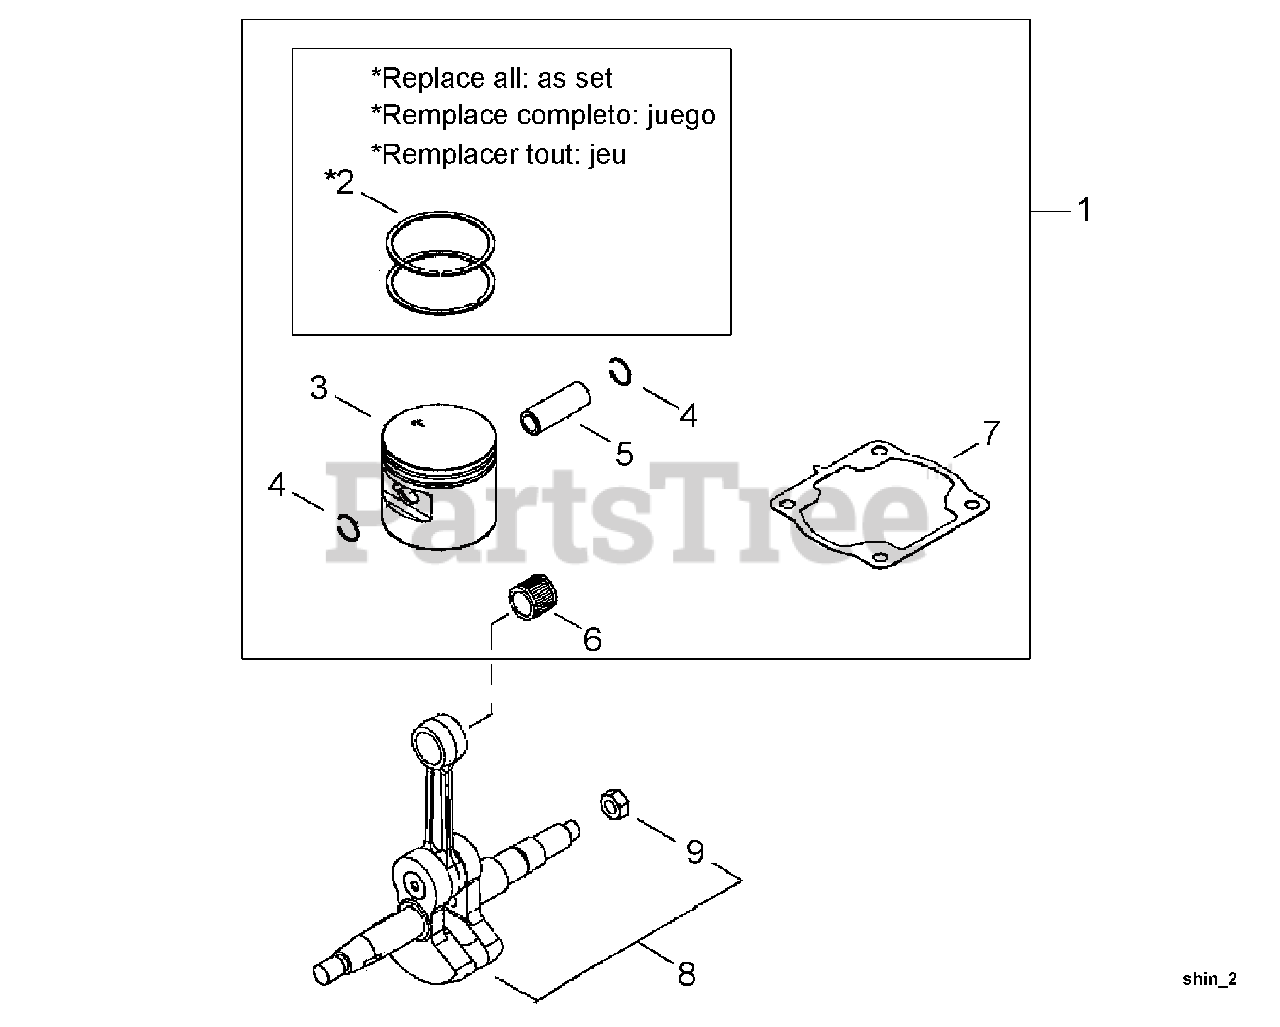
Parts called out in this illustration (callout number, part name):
1	PISTON KIT
2	RING, PISTON
4	RING, SNAP
5	PIN, PISTON 10
6	BEARING, NEEDLE
7	GASKET, CYLINDER
8	CRANKSHAFT ASSY
9	NUT M8
